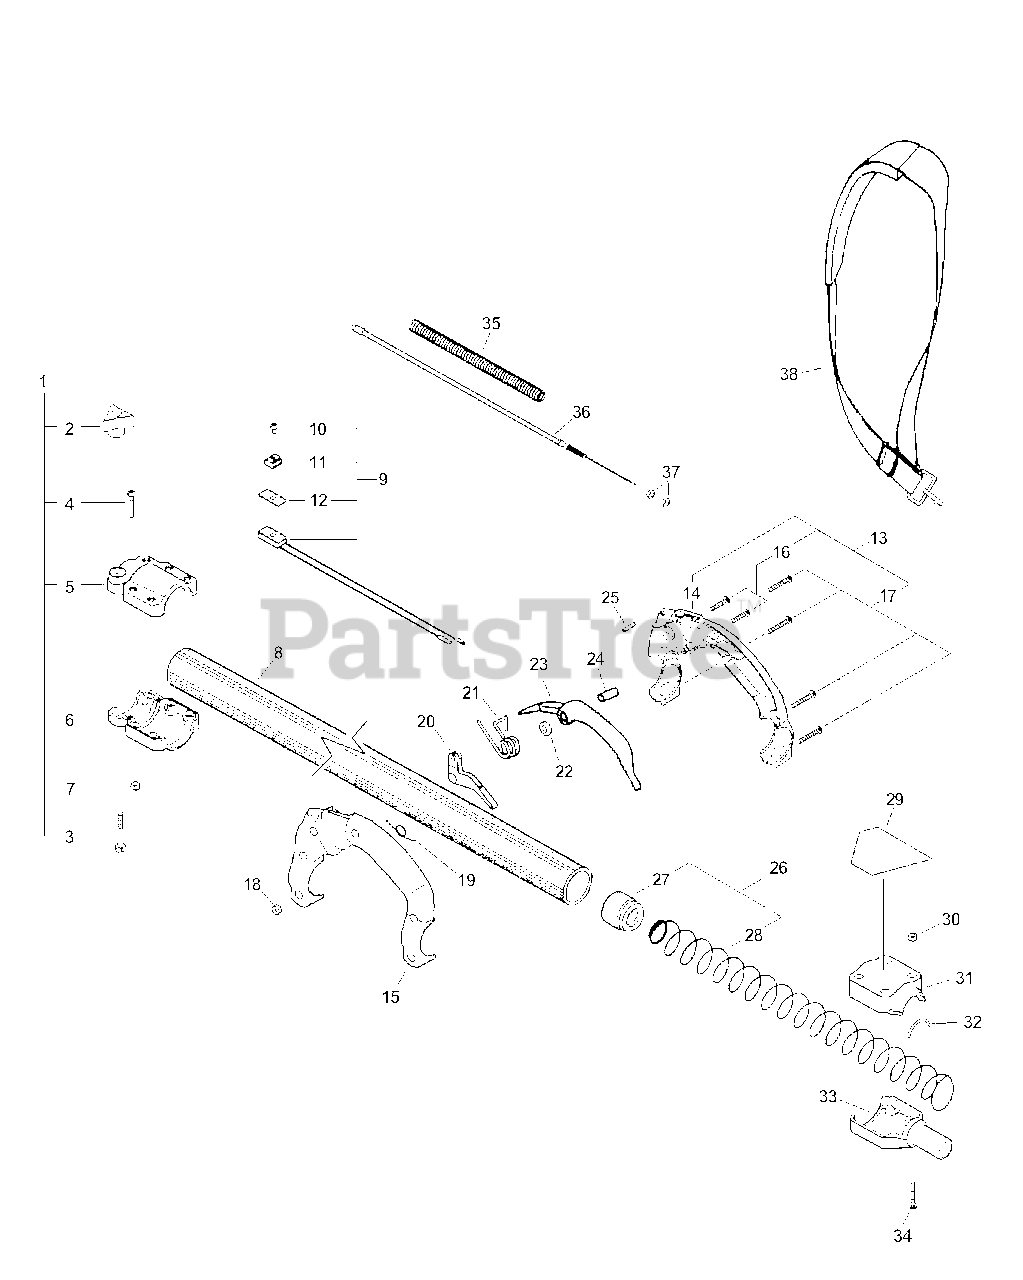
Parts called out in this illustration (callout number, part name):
1	COLLAR ASSY
2	THUMBSCREW
4	SCREW - 10-24 X 1-1/4"
5	COLLAR, MAIN PIPE - UPPER
6	COLLAR, MAIN PIPE - LOWER
7	LOCKNUT - 10-24
8	PIPE, MAIN - ORANGE
9	IGNITION SWITCH ASSY
10	SCREW - 3X10
11	KNOB, SWITCH - ORANGE
12	COVER, SWITCH - STOP
13	HANDLE ASSY - REAR
14	HANDLE, REAR - RIGHT
15	HANDLE, REAR - LEFT
16	SCREW - 10-24 X 1-1/4"
18	LOCKNUT - 10-24
19	SPRING, TRIGGER
20	TRIGGER, THROTTLE
21	SPRING, LOCKOUT LEVER
22	WASHER - 5
23	LOCKOUT, THROTTLE
24	COLLAR - 5
25	PIN - LOCATING
26	FLOATING BUSHING ASSY
27	BUSHING, FLOATING
29	LABEL - CAUTION
30	LOCKNUT - 10-24
31	CAP, LOWER SHAFT TUBE ADAPTER
33	ADAPTER, LOWER SHAFT TUBE
35	TUBE, PROTECTIVE - CORRUGATED
36	CABLE, THROTTLE
38	SHOULDER STRAP ASSY
